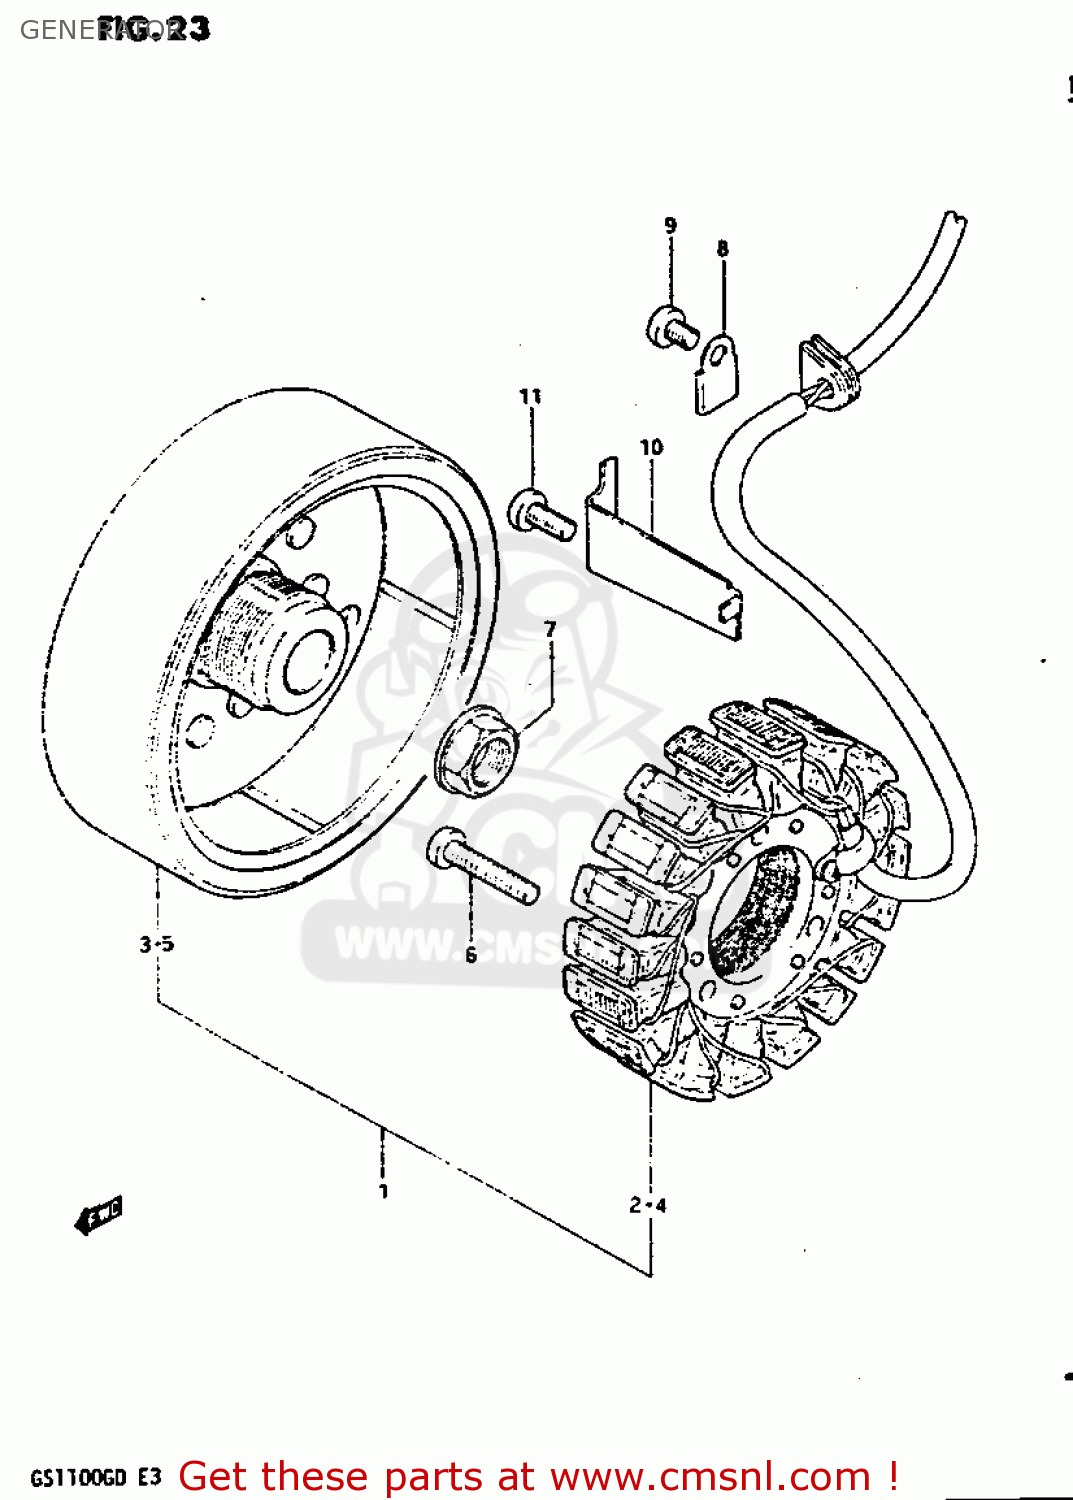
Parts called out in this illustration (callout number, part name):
1	STARTER ASSY
2	STARTER ASSY
3	ROTOR ASSEMBLY
4	STARTER ASSY
5	ROTOR ASSEMBLY
6	SCREW 6X30
7	NUT,GENERATOR ROTOR
8	CLAMP,GENERATOR LEAD WIRE
9	SCREW
10	CLAMP,GENERATOR LEAD WIRE
11	SCREW
